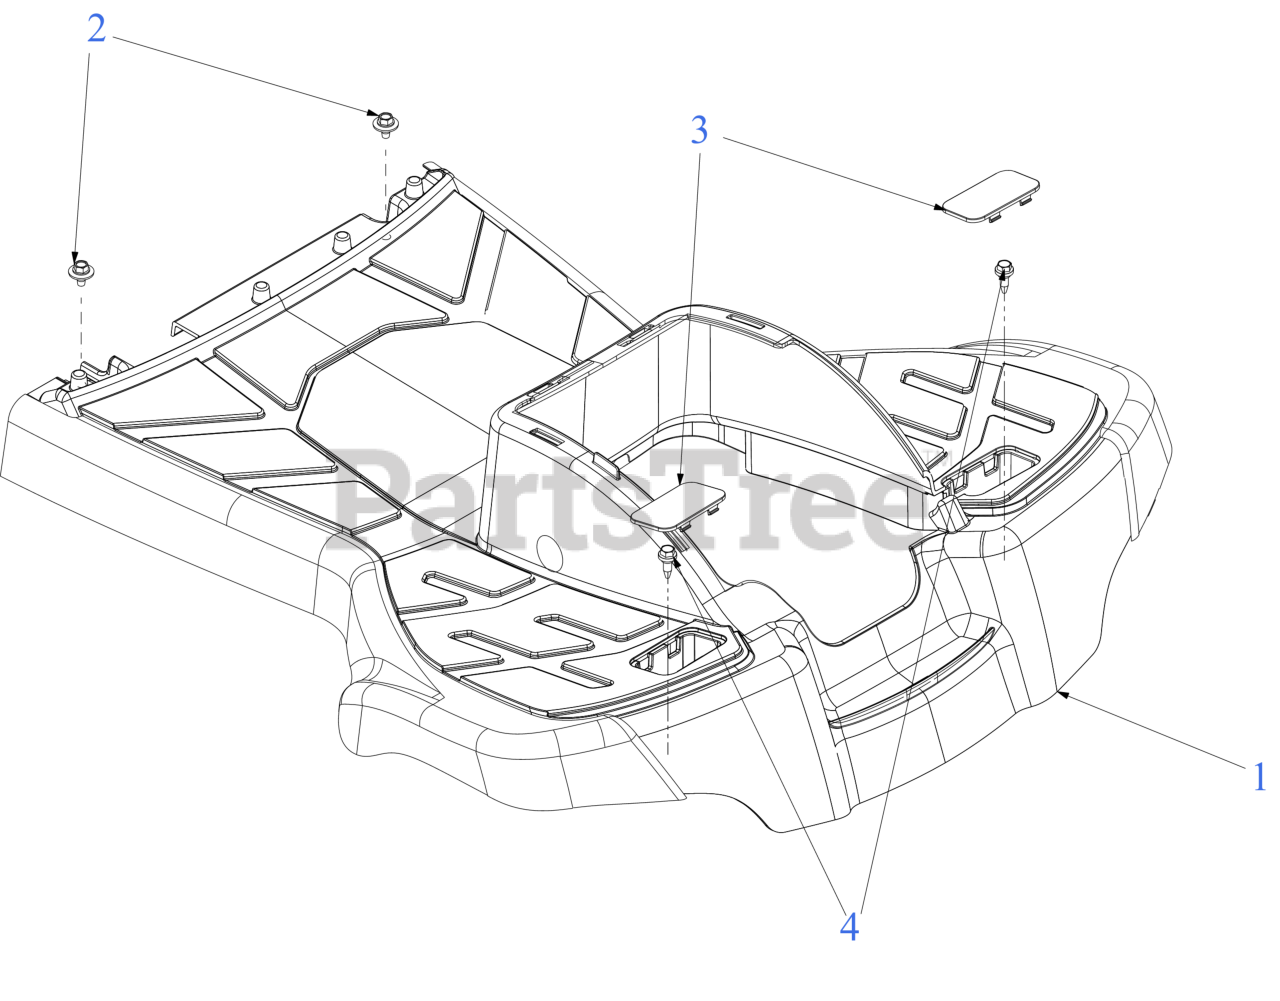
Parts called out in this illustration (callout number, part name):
1	RUNNINGBOARD W/RMC (MTD RED)
2	SCREW 1/4-20 x .50
3	RUNNING BOARD PLUG
4	SHOULDER SCREW
